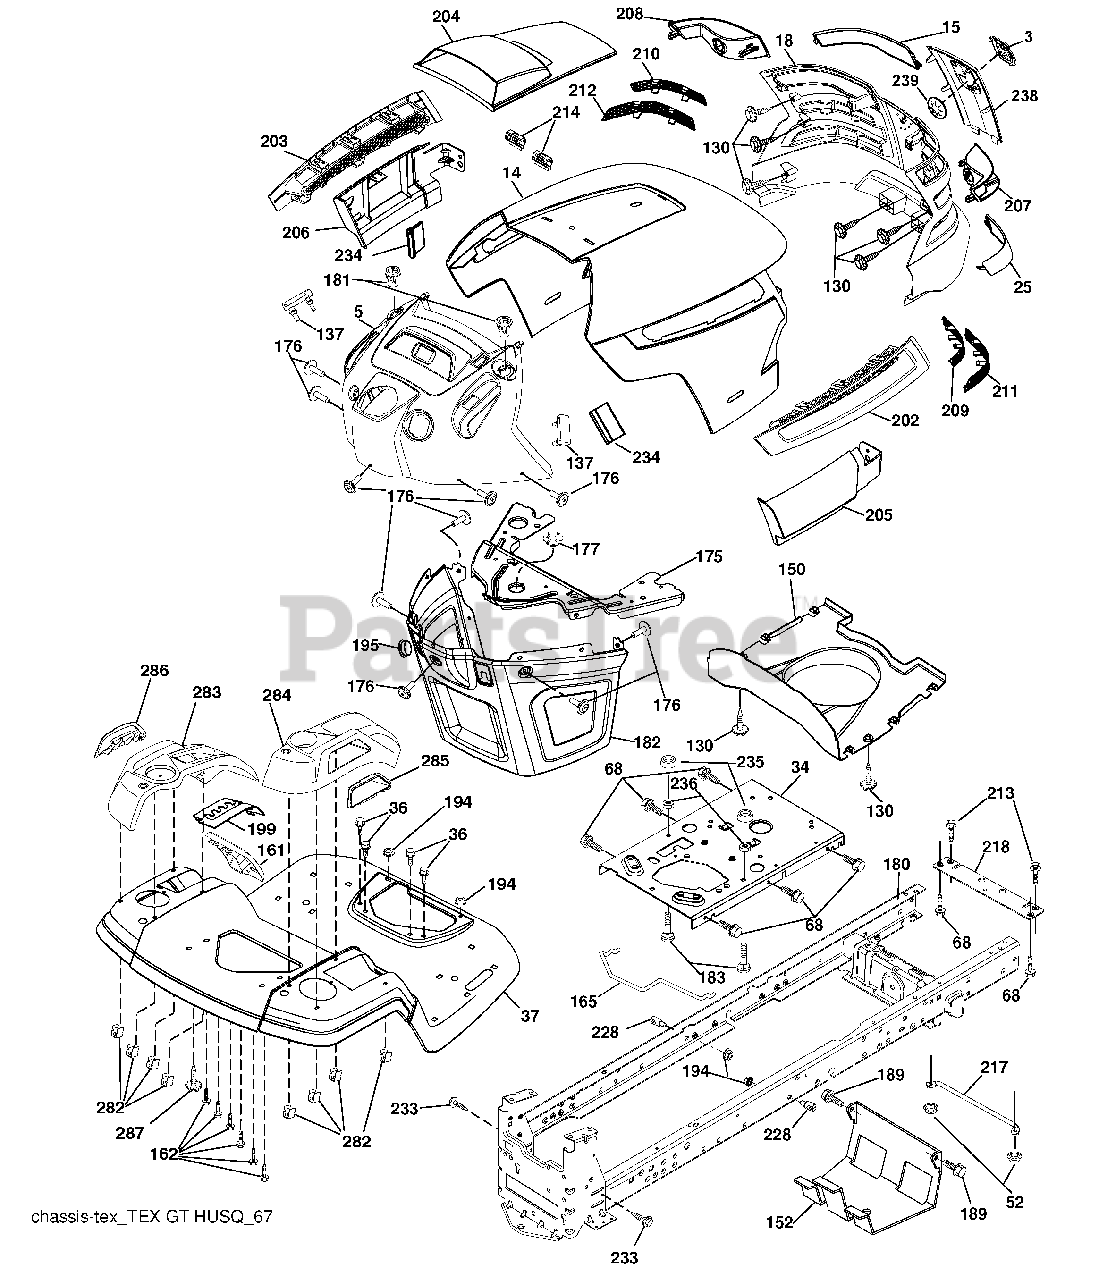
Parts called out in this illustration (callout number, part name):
3	Logo
14	Hood
18	Grille Asm.
34	Plate Engine
36	Screw 5/16-18 x 3/4
52	Nut Lock 5/16-18
68	Screw 5/16-18 x 1/2
130	Screw #10 x 0.750 BOS Thread
137	Bumper Dash
152	Shield Browning
161	Window Fuel
165	Support Tank Rear
175	Crossmember
176	Screw 10-24 x 5/8
177	Bushing Steering
180	Chassis
181	Bushing Mtg. Fender Crgo
182	Dash Lower
183	Bolt 5/16-18 x 1-1/4
189	Screw 5/16-18 x 3/4
194	Nut Lock Hex Flange 5/16-18
195	Plug Hole Dash Lower
199	Plate Deck Lift
202	Vent Side Hood RH
203	Vent Side Hood LH
204	Vent Top Hood
205	Skirt Hood Side RH
206	Skirt Hood Side LH
209	Insert Hex Top RH
210	Insert Hex Top LH
211	Insert Hex Bottom RH
212	Insert Hex Bottom LH
213	Bolt 5/16-18 unc x 3/4
214	Clip Retainer Tinner
218	X-Piece Hood Stop
228	Stud Fastner
233	Bolt, Shoulder
234	Bumper Hood
235	Spacer Fender
236	Nut Lock 5/16-18 unc
282	Clip Retainer Console
283	Console Asm. Decklift
284	Console Asm.
285	Console Insert RH
286	Console Insert LH
287	Screw Hex Washead 1/4-20 x 3/8
